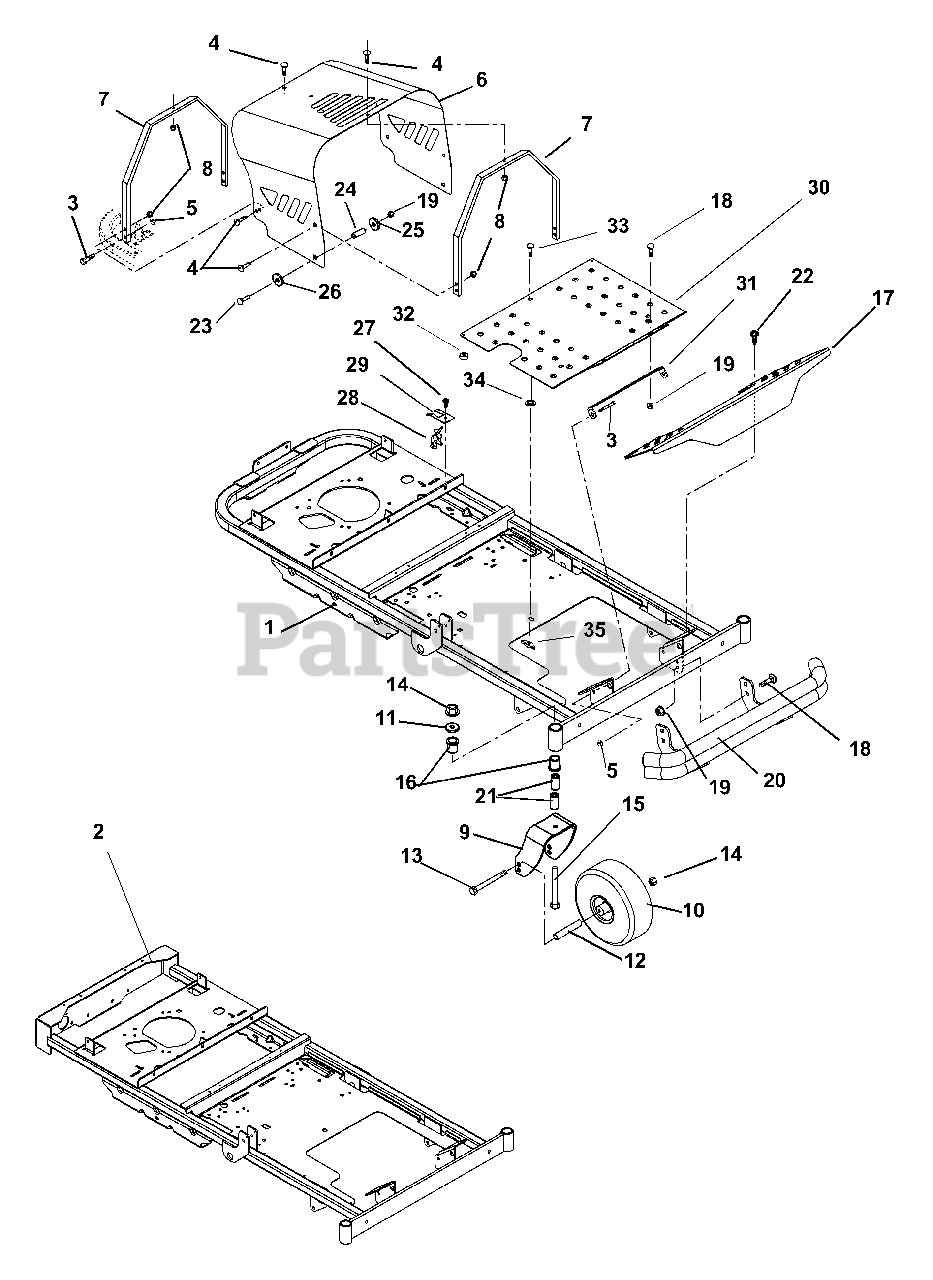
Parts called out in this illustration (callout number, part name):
1	WMT, FIXED AXLE FRAME
2	WMT, FRAME (CE FIXED)
3	BOLT-SHLDR .375-16X.150
4	@BLT-RHDSSQNK .31-18X.62 G5YZ
5	@NUT-LK-TOP-FLG .38-16 YWZC
6	ENGINE HOOD, CE ZOOM
7	BRACE, HOOD
8	@NUT-LK-TOP-FLG .31-18 YWZC
9	FORK, CASTER- WELDED
10	ASSY-TIRE 4 X 11 - 4 PLY
11	WSHR-FL-STL.511X1.441X.125 YWZ
12	SPACER, ROLLED WHEEL
13	@BLT-HEX .50-13X6.50 GR5 YWZC
14	@NUT-LK-TOP-FLG .50-13 YWZC
15	@BLT-HEX .50-13X5.00 GR5 YWZC
16	BSHG-FLG 1.00X1.25X1.50X1.50EP
17	FOOTREST
18	@BLT-RDHDSQNK .38-16X1.00 G5YZ
19	@NUT-LK-NYL-FLG .38-16 YWZC
20	WMT, BUMPER
21	SPACER, CASTER .50X1.00X1.84
22	@SCR-TAP .31-18X.50 HWH TR YWZ
23	@BLT-RDHDSQNK .38-16X2.00 G2YZ
24	BSHG, SPCR .390X.625X1.25 PM
25	WSHR-FL-STL .375X1.125X.065YWZ
26	@WSHR-FL-STL.531X1.06X.095YWZC
27	@SCR-TAP .25-20X.50 HWH TR YWZ
28	HOOD CLIP
29	BRACKET, HOOD CLIP
30	PLATE, DECK ACCESS
31	BRACKET, DECK ACCESS
32	BUMPER GROMMET
33	@BLT-RDHDSQNK .31-18X1.00 G5YZ
34	NUT-PUSH .312
35	KNOB - WING .312-18 UNC
